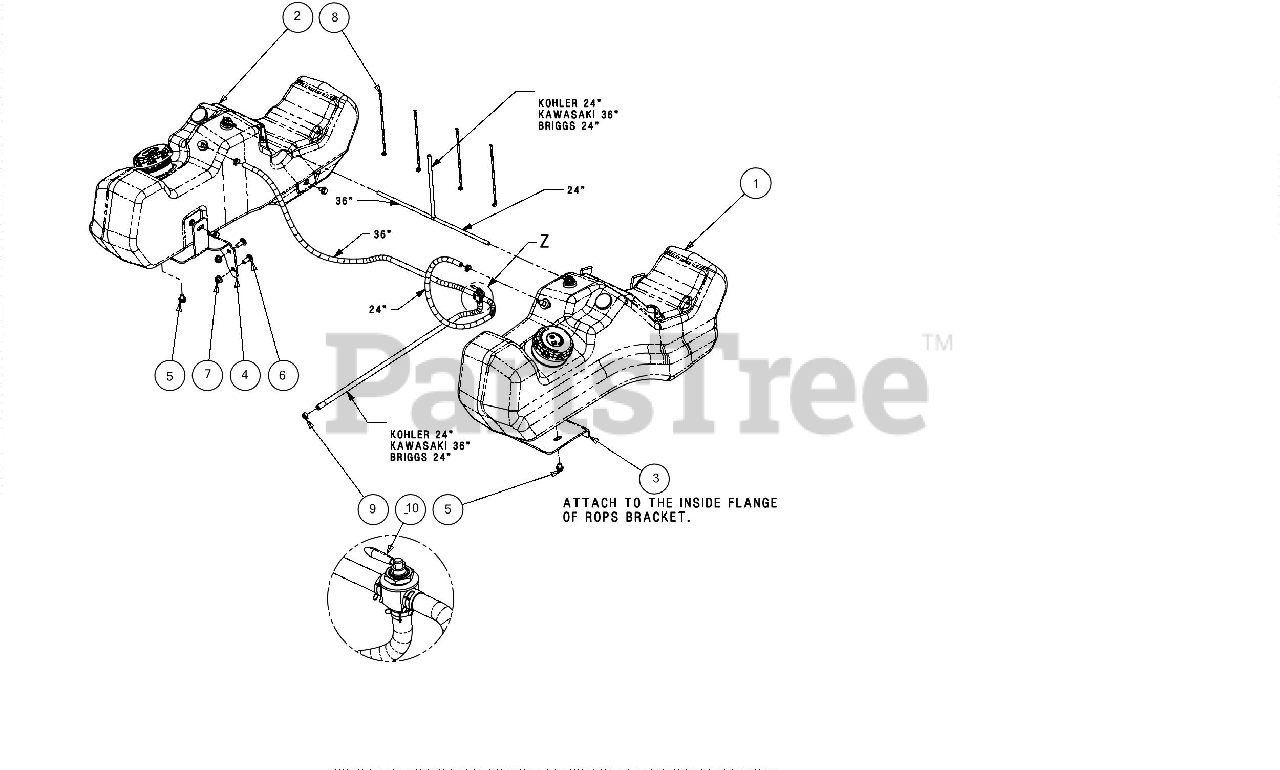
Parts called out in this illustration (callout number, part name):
1	FUEL TANK ASSEMBLY (RH)
2	FUEL TANK ASSEMBLY (LH)
3	REAR FUEL BRACKET (RH)
4	REAR FUEL BRACKET (LH)
5	SCREW 3/8-16 X .500 GR5
6	CARRIAGE BOLT 3/8-16 X 1.00 GR5
8	CABLE TIE 7"
10	3 WAY FUEL SWITCH
